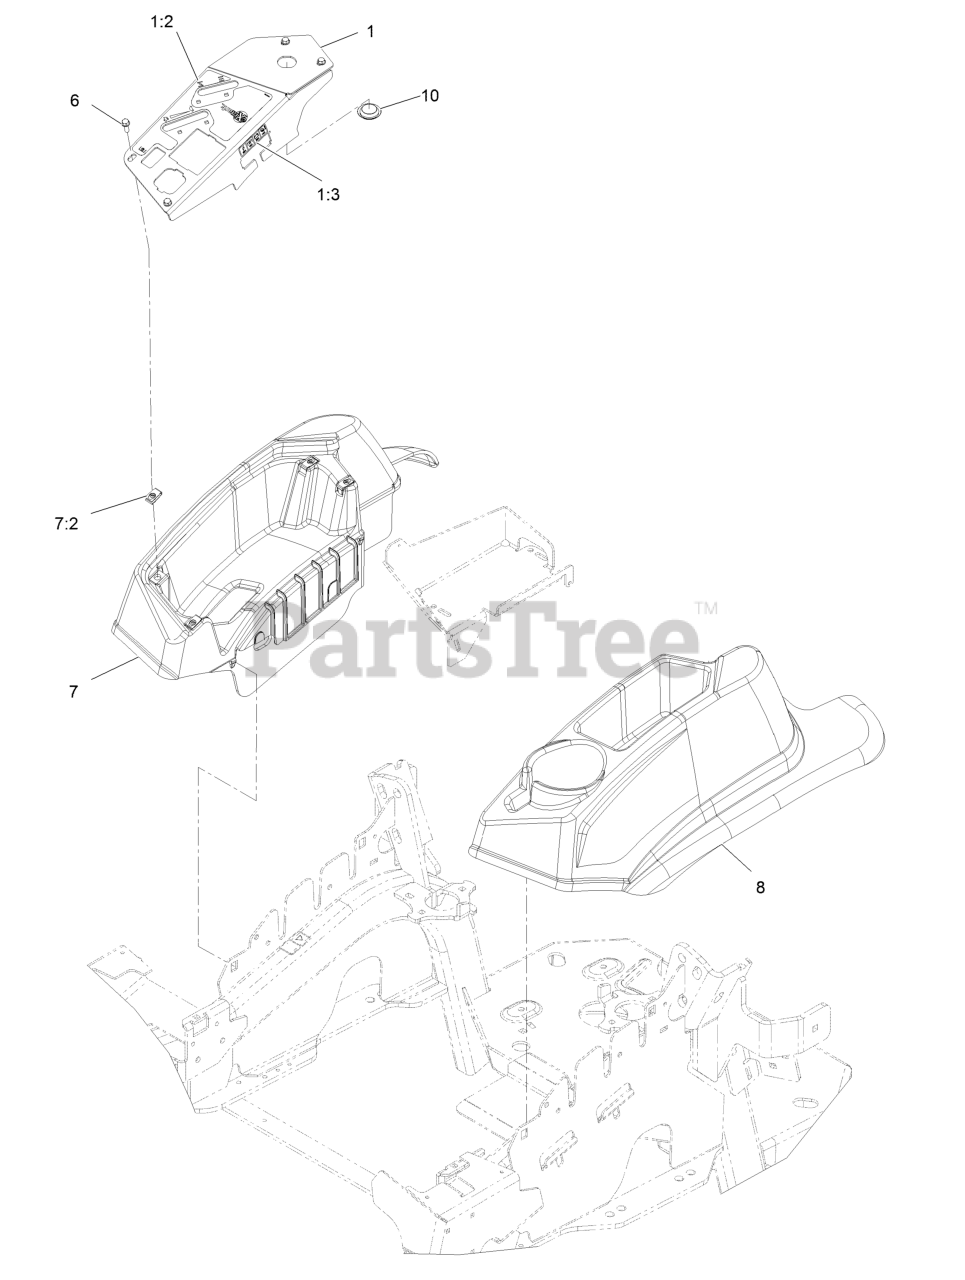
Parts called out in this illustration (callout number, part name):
1	Console,Panel W/Decal
1:2	Decal-Control Panel Non-Efi
1:3	Decal-Fuses
6	Screw-Machine 1/4-20 X 3/4
7	Console,RH As ASM
7:2	Nut-Retainer-Panel 1/4-20
8	Console, LH As
10	Plug-Plastic
